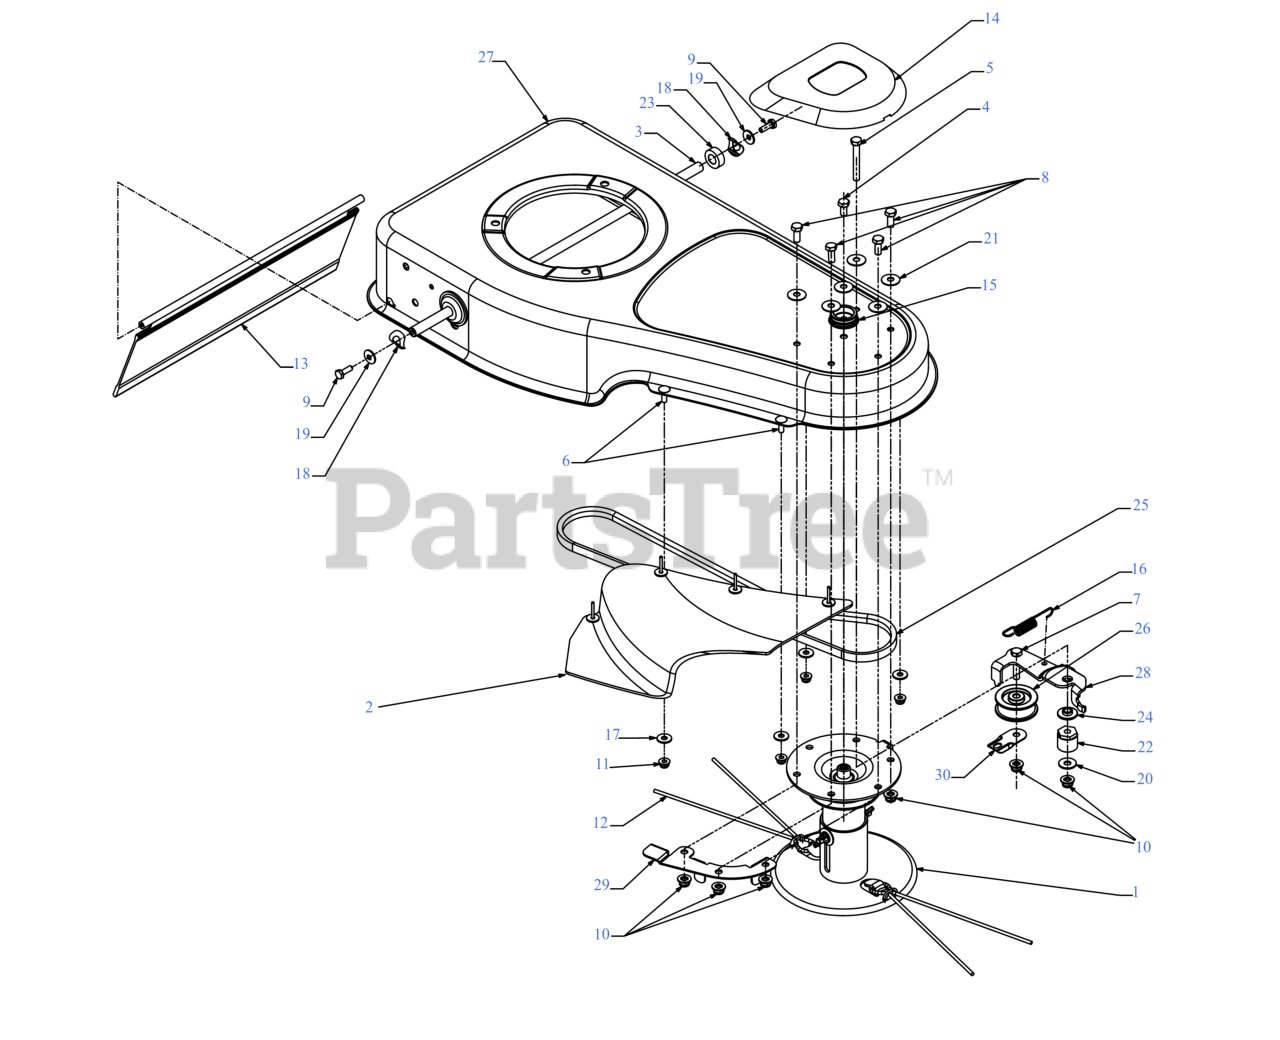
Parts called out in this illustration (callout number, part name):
1	SPINDLE ASSEMBLY
2	22" DEFELECTOR ASSEMBLY
3	AXLE ASSEMBLY
4	HEX SCREW 5/16-24 x .62
5	HEX SCREW 5/16-18 x 2.25 GR5
6	SCREW 1/4-20 x .75 GR5
7	SCREW 5/16-18 x 1.5 LG
8	SCREW 5/16-18 x .75 GR5
9	SCREW 1/4-20X.75 GR5
10	FLANGE LOCK NUT 5/16-18
11	FLANGE LOCK NUT
12	TRIMMER LINE: 10 P
13	TRIMMER TRAILSHIELD
14	COVER TRIM
15	COVER TRIM RETAINER
16	EXTENSION SPRING .500 OD x 3.375
17	FLAT WASHER .28 ID x .74 OD x .063
18	SPRING WASHER .50 x 1.0 x .022
19	SPRING WASHER BELL
20	FLAT WASHER
21	BELL WASHER
23	SPACER .51
24	IDLER SPACER
25	V-BELT 4L x 44.6"
26	IDLER PULLEY
28	IDLER BRACKET
